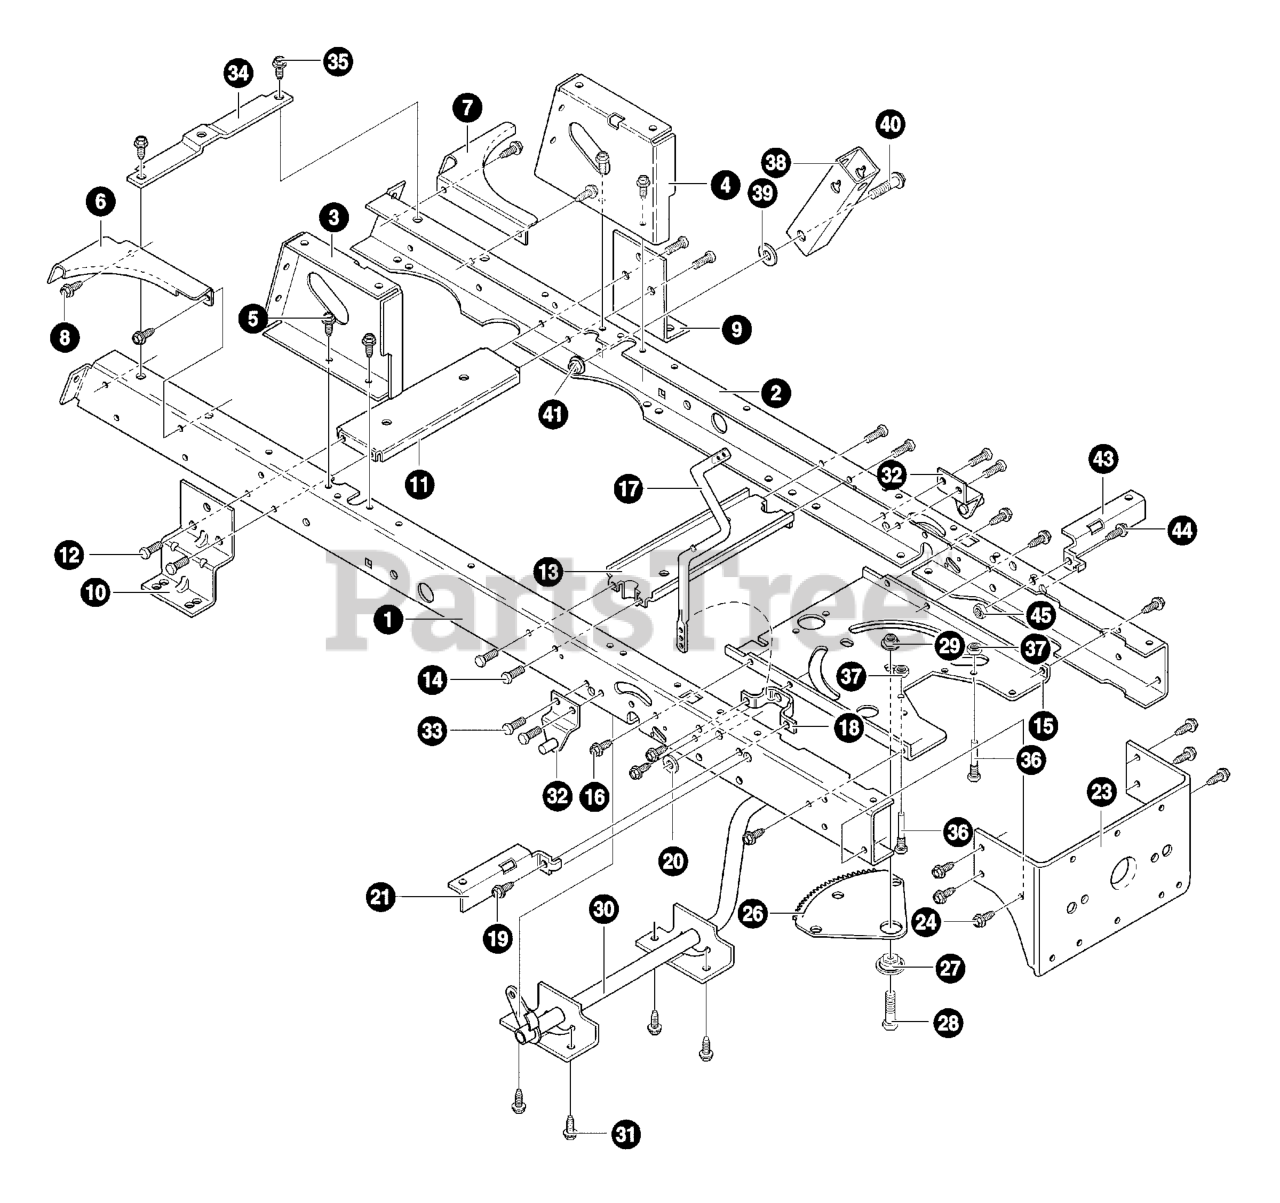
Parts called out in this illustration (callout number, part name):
1	FRAME, RAIL RH
2	FRAME, RAIL LH
3	SUPPORT, SEAT RH
4	SUPPORT, SEAT LH
5	SCREW, 5/16-18 x .75 HHWATAP
6	BRACE, BACKPLATE RH
7	BRACE, BACKPLATE LH
8	SCREW, 5/16-18 x .75 HHWATAP
9	BRACKET, TRANSAXLE
10	BRACKET, T/A RH-VST LH-MS
11	ASM., IDLER MOUNT, REAR
12	SCREW, 5/16-18 x .75 HHWATAP
13	ASM. IDLER MOUNT FRONT
14	SCREW, 5/16-18 x .75 HHWATAP
15	PLATE, STEERING MOUNTING
16	SCREW, 5/16-18 x .75 HHWATAP
17	CRANK, PTO DRILLED
18	BRACKET, BELL CRANK
19	SCREW, 5/16-18 x .75 HHWATAP
20	WASHER, FLAT .469X.92X.065
21	BRACKET, SEAT DECK LH
23	BRACKET HANGER REAR
24	SCREW, 5/16-18 x .75 HHWATAP
26	GEAR, SECTOR
27	BEARING, SECTOR GEAR
28	SCREW 5/16-18X1.00
29	NUT, 5/16-18 HEXKEPS
30	ASM., CLUTCH/BRAKE PEDAL STD.
31	SCREW, 5/16-18 x .75 HHWATAP
32	BRACKET, SUSPENSION ASM.
33	SCREW, 5/16-18 x .75 HHWATAP
34	BRACE, RAIL
35	SCREW, 5/16-18 x .75 HHWATAP
36	ZINC SCRW GUIDE 5/16-18
37	NUT, 5/16-18 HEXWDFLLK WHIZ
38	BRACKET, PIVOT
39	WASHER, FLAT .390X1.25X.119
40	BOLT, .562X1.563 HHSH 3/8-16
41	NUT, 3/8-16 HWDFLLK MACK
43	BRACKET, SEAT DECK LH
44	SCREW, 5/16-18 x .75 HHWATAP
45	NUT, 5/16-18 HEXWDFLLK WHIZ
